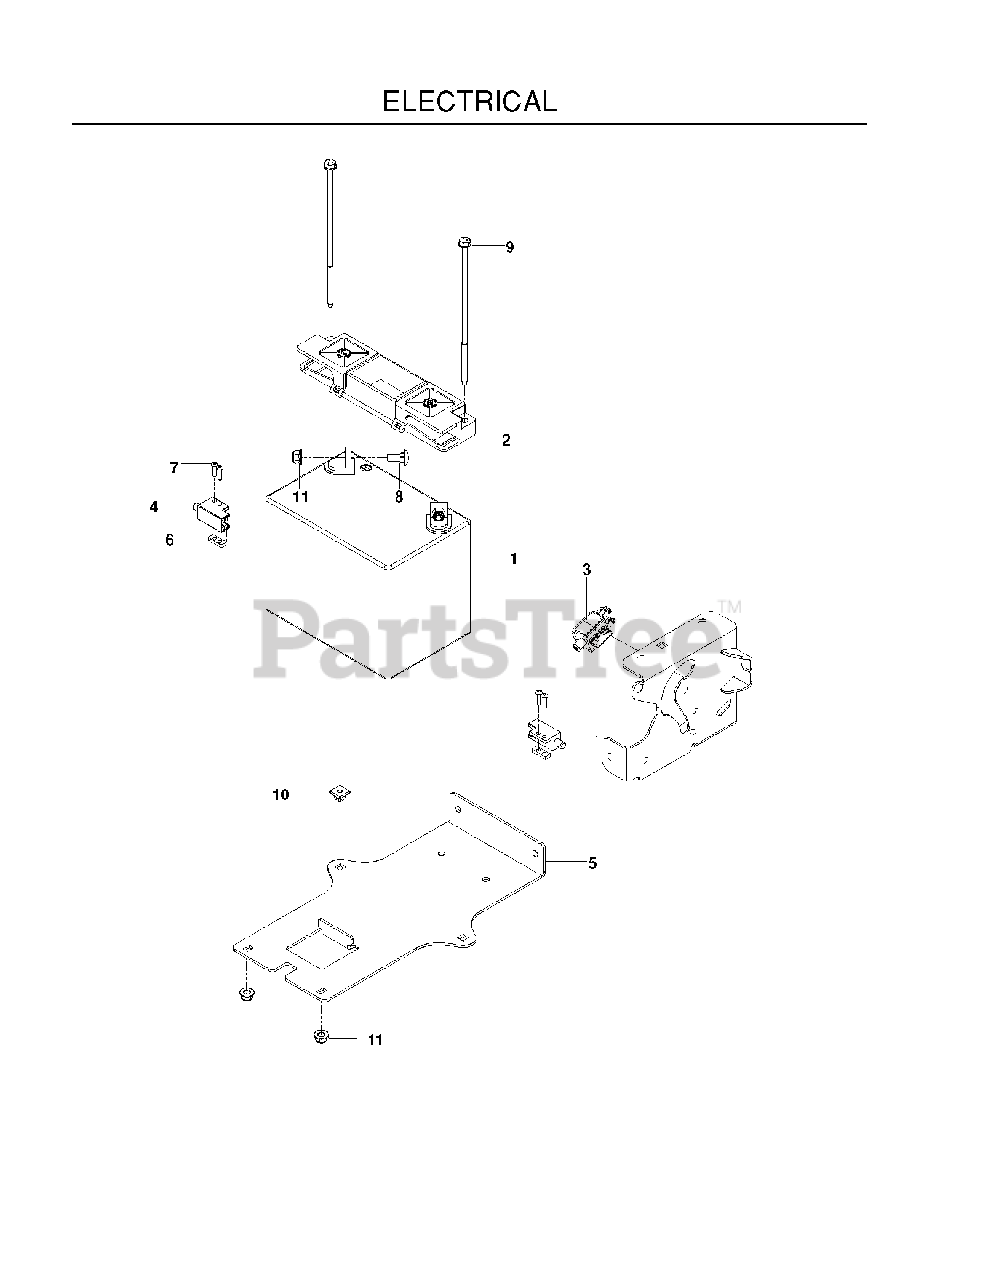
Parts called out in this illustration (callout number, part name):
1	BATTERY, 12 V 330 AMP
2	BATTERY HOLD DOWN
3	SWITCH, BRAKE 3P
5	PLATE, BATTERY, BLACK
6	TAPPED PLATE
7	SCR #10-24 X .75 SKT HD BLK
8	BOLT 5/16C X 3/4" CARRIAGE
9	BOLT - 1/4-20 X 7.5
10	PUSH NUT-NYLON
11	5/16-18 NYLOC FLANGE NUT
